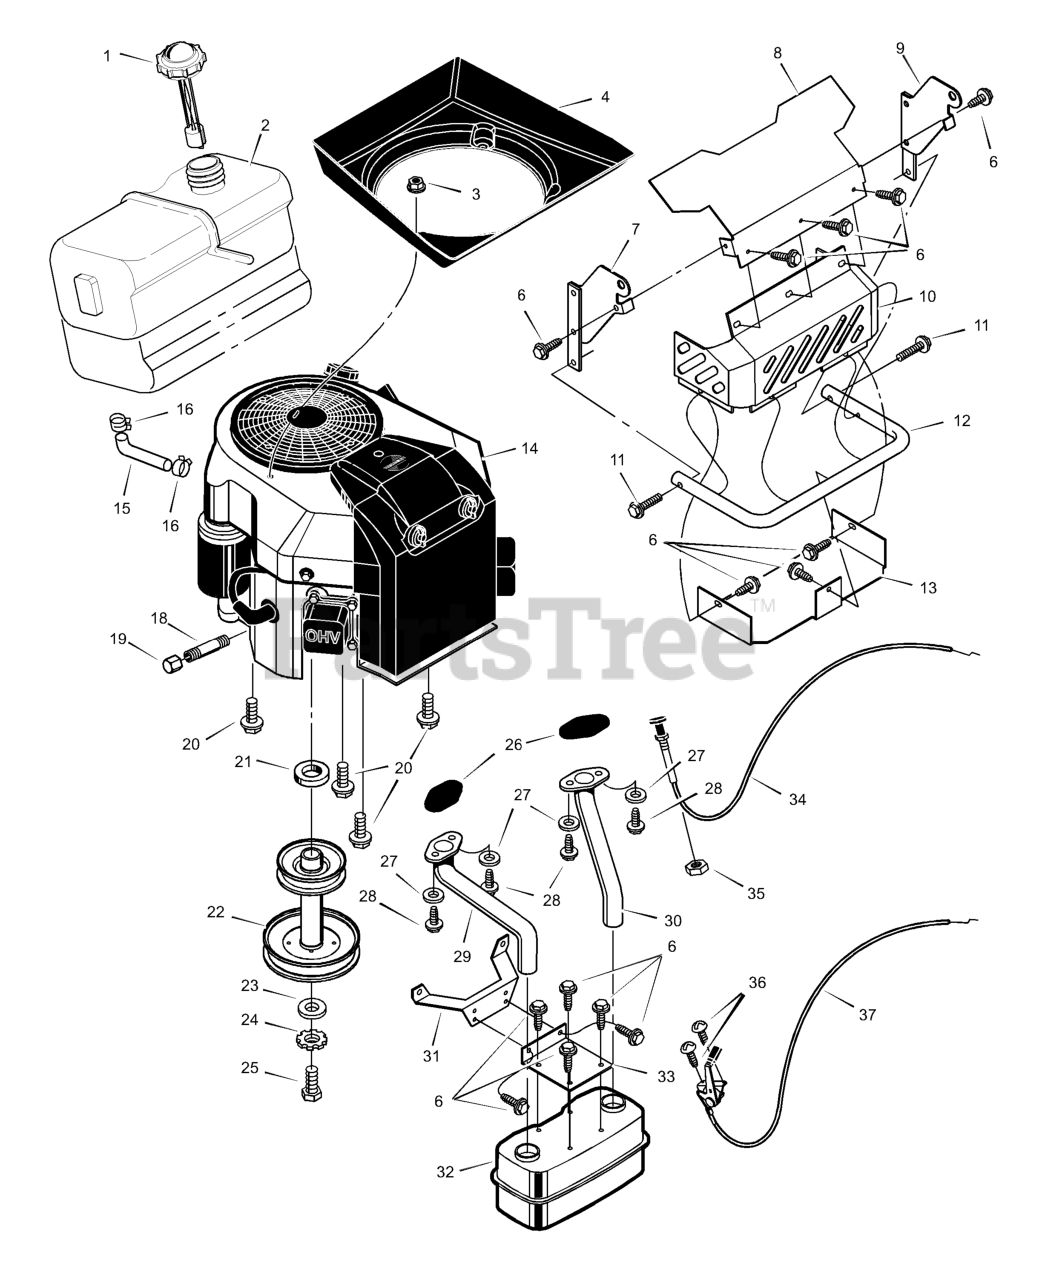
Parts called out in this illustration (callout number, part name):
1	Cap, Fuel
2	Tank, Fuel
3	Nut
4	Plenum, Air Intake
7	Assembly, Right Grille Support
8	Shield, Heat
9	Assembly, Left Grille Support
10	Shield, Heat
13	Shield, Lower
14	Engine *
15	Line, Fuel (17 inches long)
16	Clamp
18	Pipe, Oil Drain
19	Cap, Oil Drain
20	Bolt
22	Pulley, Stack
24	Lockwasher
27	Washer
28	Bolt
29	Tube, Right Exhaust
30	Tube, Left Exhaust
31	Bracket, Muffler Mount
32	Muffler
33	Bracket, Muffler
35	Nut
37	Control, Throttle
